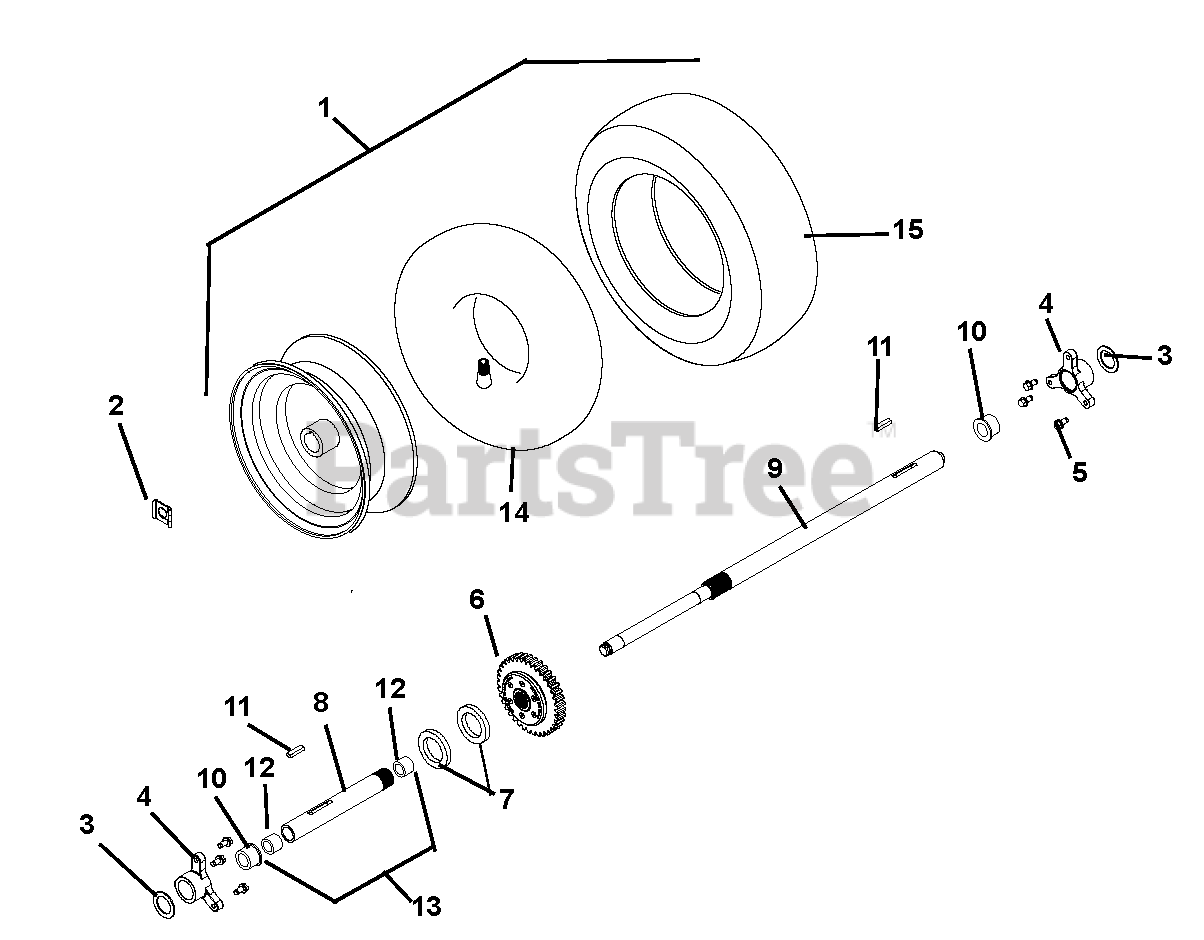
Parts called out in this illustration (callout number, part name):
1	Tire/Wheel Assembly RH 16 x 6.50 - 8 Differential (Includes 14-15)
2	Clip, Snap
3	Washer, Flat Steel 1.010 x 1.505 x .062
4	Bushing, Rake Shaft 1"
5	Screw, Tapping .25-20 x .50
6	Differential, Hilliard
7	Washer, Flat Steel 1.062 x 2.00 x .134
8	Axle, Differential-Short
9	Axle, Differential-Long
10	Bushing, Flange Split Nyliner 1.0" HP
11	Key .25 x .188 x 1.00
12	Bushing, Sleeve
13	Axle, Differential with Bushings (Includes 8 and 12)
14	Tube 16 x 6.50- 8
15	Tire, X-TRAC 16 x 6.5-8
